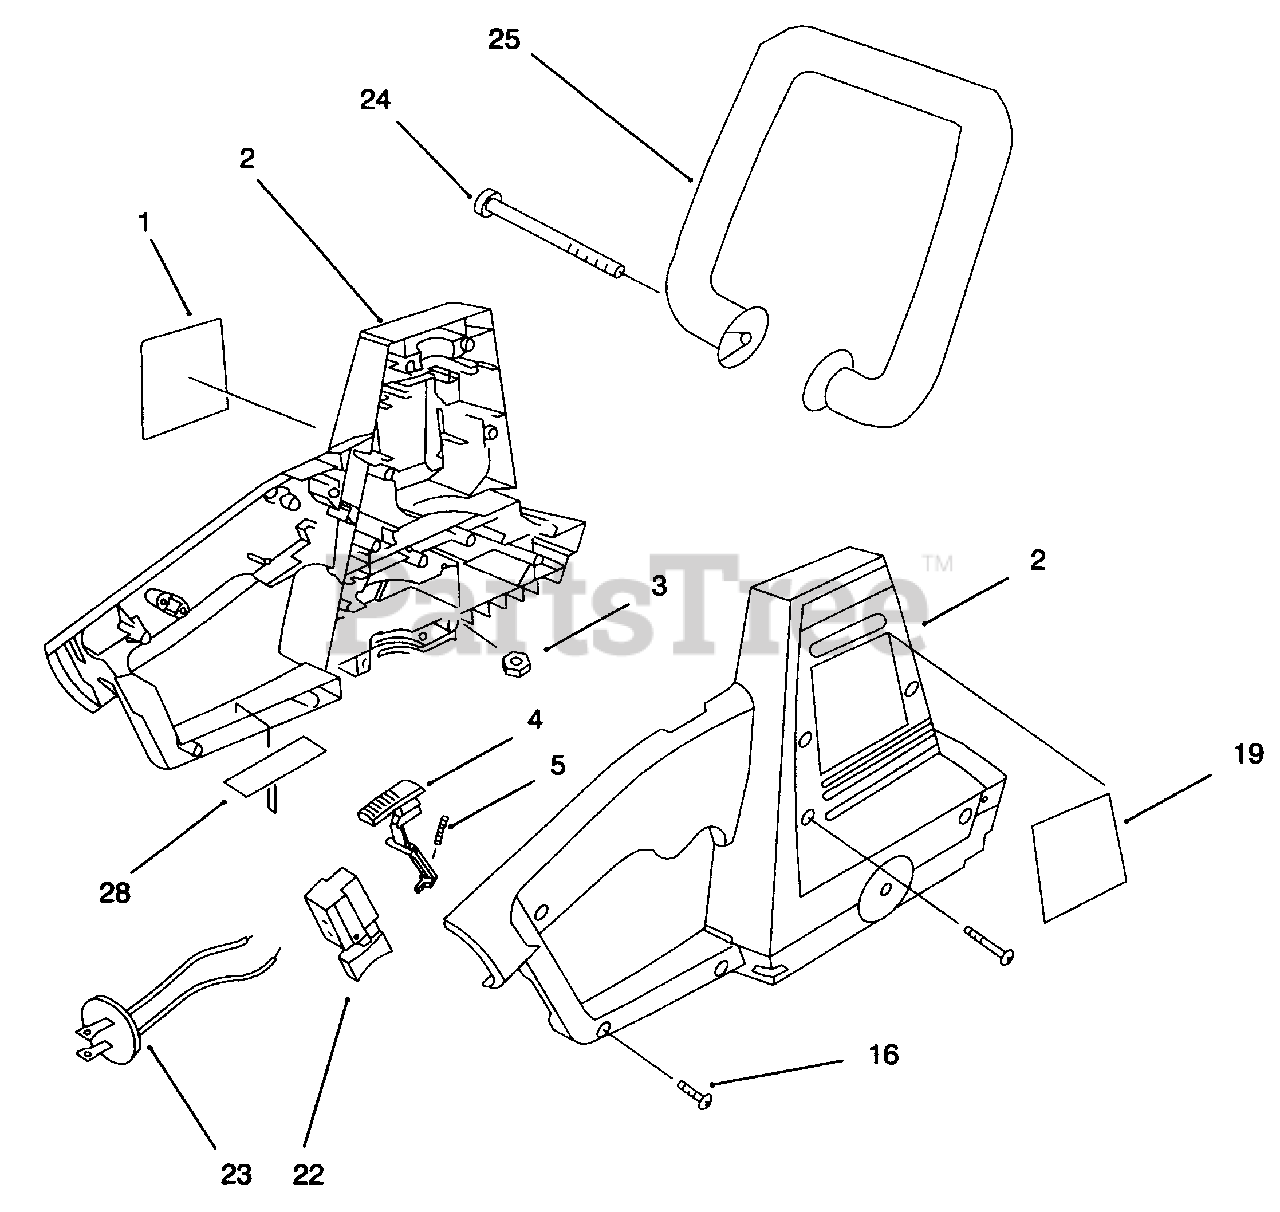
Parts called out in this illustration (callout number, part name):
1	LOGO PLATE (51815)
2	HOUSING ASSEMBLY
3	HEX NUT
4	LOCK-OFF BUTTON
19	WARNING LABEL
23	DISC ASSEMBLY
25	FRONT HANDLE
28	DATA PLATE (51815)
